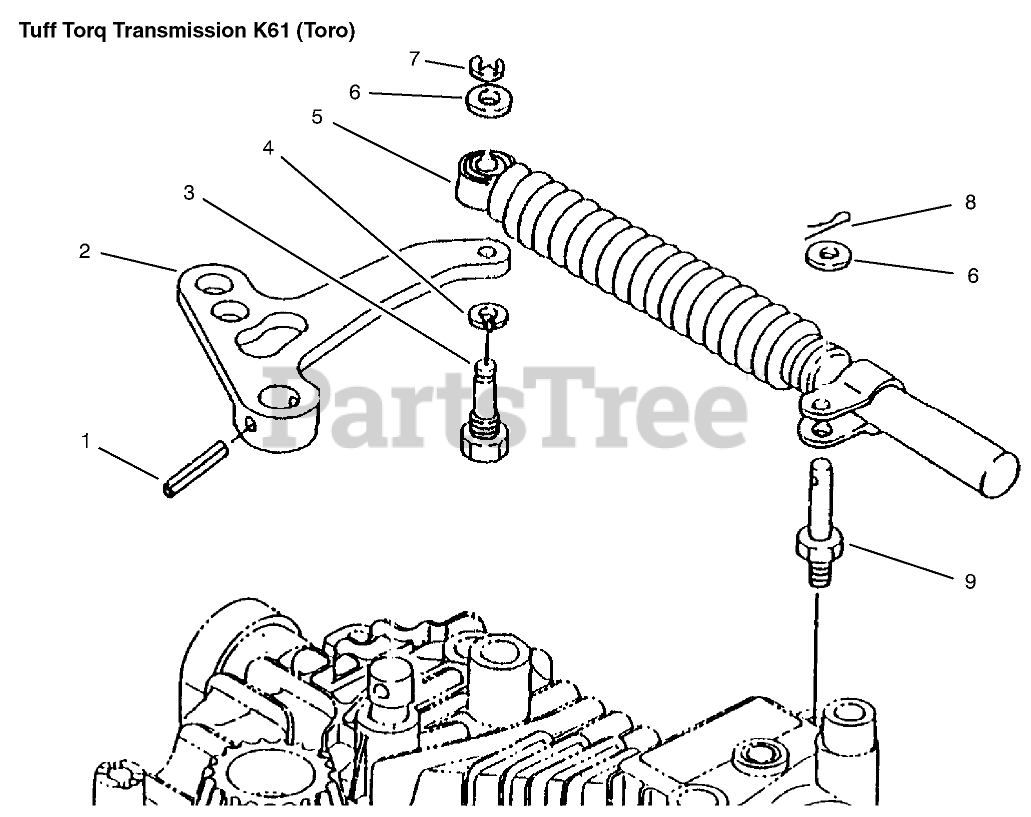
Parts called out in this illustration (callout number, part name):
1	PIN-ROLL
3	BOLT-KIT
4	WASHER
5	SHOCK ABSORBER KIT
6	WASHER
8	PIN-COTTER
9	STUD-KIT
